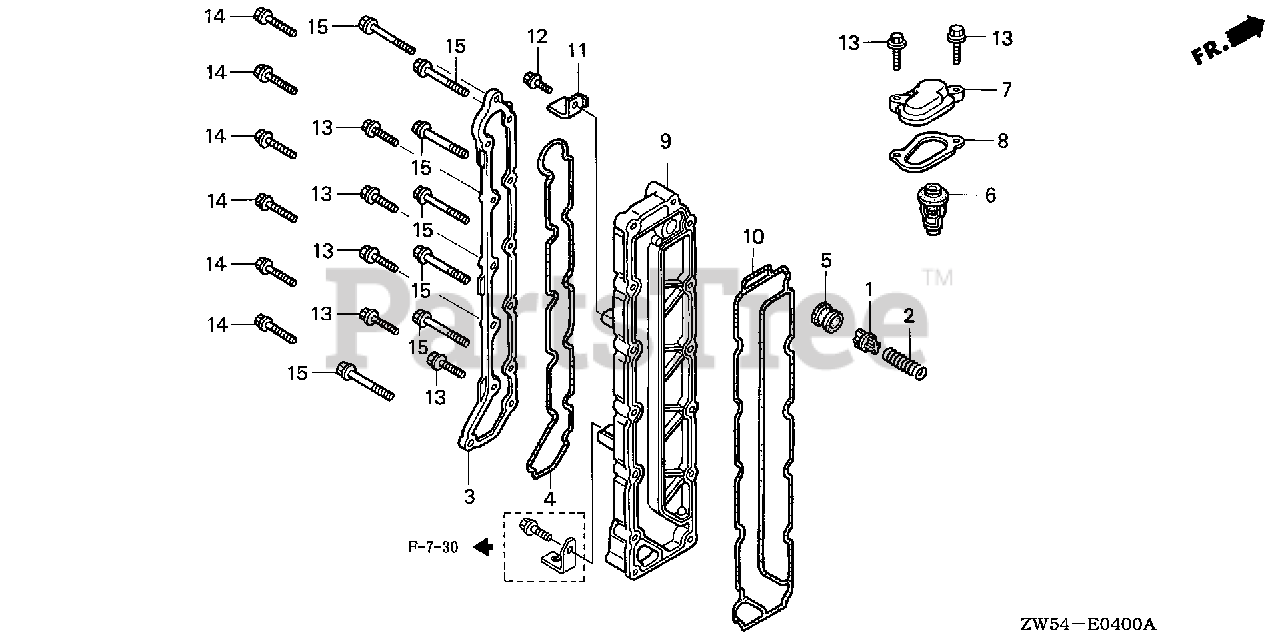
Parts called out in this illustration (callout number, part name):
1	VALVE, RELIEF
2	SPRING, RELIEF VALVE
3	COVER, RELIEF VALVE *NH8* (DARK GRAY)
4	GASKET, RELIEF VALVE COVER
5	GASKET, RELIEF VALVE
6	THERMOSTAT ASSY.
7	COVER, THERMOSTAT
8	GASKET, THERMOSTAT COVER
9	COVER, WATER JACKET *NH8* (DARK GRAY)
10	GASKET, WATER JACKET COVER
11	STAY A, IGNITION WIRE CLAMP
12	BOLT, FLANGE (6X12)
13	BOLT, FLANGE (6X20)
14	BOLT, FLANGE (6X25)
15	BOLT, FLANGE (6X45)
